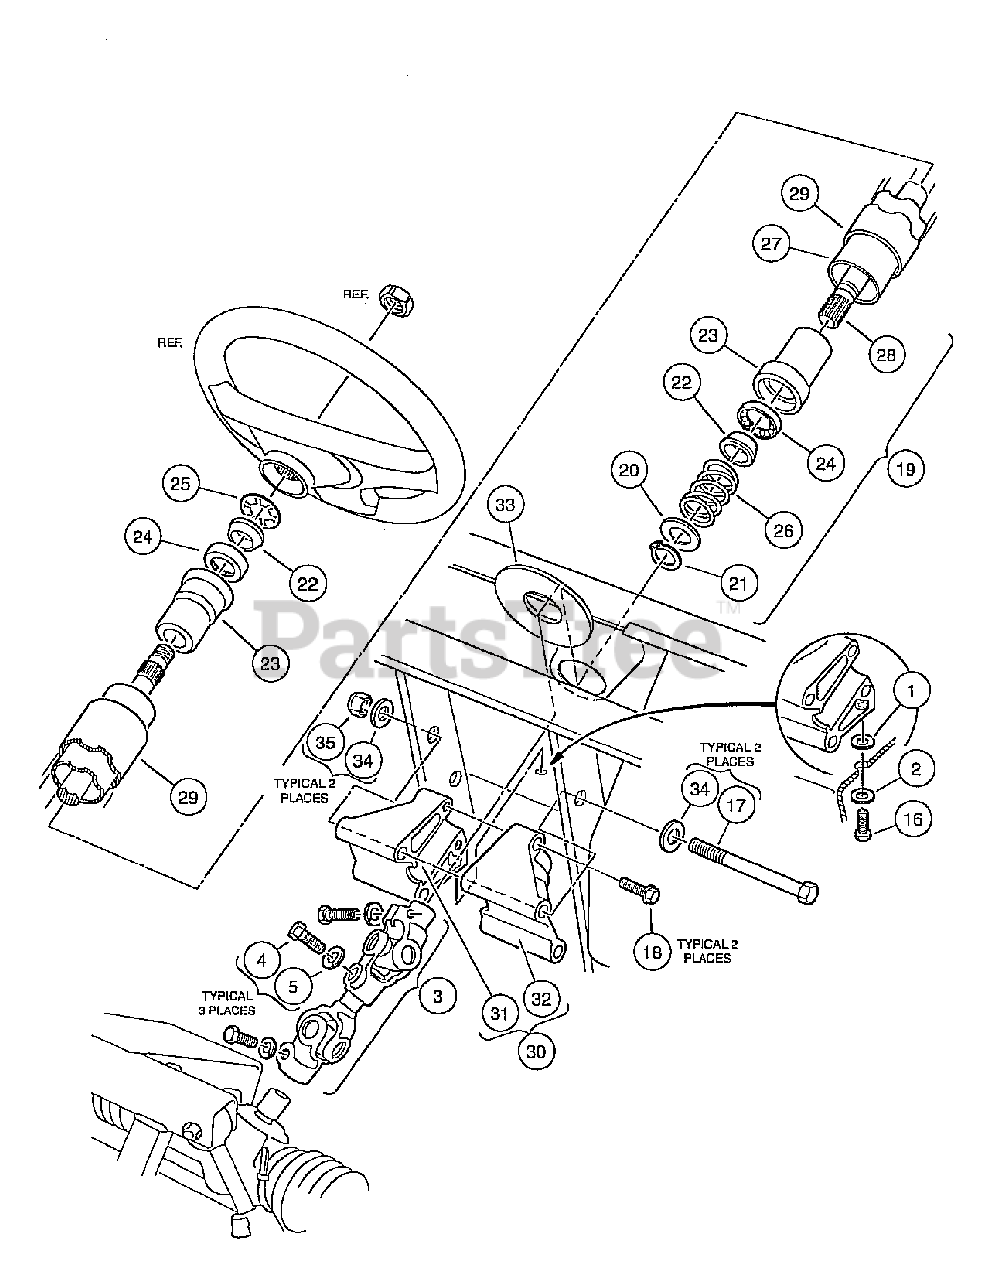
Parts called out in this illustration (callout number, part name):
1	Washer, 5/16 Type B Flat
2	Washer, 5/16 Flat
3	Intermediate Steering Shaft
4	Bolt, Hex-Head, 8mm X 1.25 - 30
5	Lockwasher, 5/16 Split
7	Dust Cover
8	Ring, 0.579 Internal Retaining
9	Wedge, Molded
10	Seat, Plastic Bearing
11	Seal, Bearing
12	Spacer, Shaft
13	Bearing, Ball
14	Ring, Retaining
15	Spring, Steering Shaft
16	Screw, 5/16-18 X 0.75 Thread-Forming
17	Screw, 3/8-16 X 7.00 Hex Cap
18	Screw, 5/16-18 Thrd Forming
19	Steering Shaft Assembly
20	Washer, 0.675 ID X 1.19 OD
21	Ring, 0.579 Internal Retaining
22	Wedge, Molded
23	Seat, Plastic Bearing
24	Bearing, Ball
25	Ring, Retaining
26	Spring, Steering Shaft
27	Column, Aluminum Steering
28	Shaft Steering Column
29	Tube Cover, Steering Column
30	Kit, Steering Column Mounting Bracket
31	Bracket, RH Steering Column Mount
32	Bracket, LH Steering column mount
33	Boot, Steering Column Round
34	Washer, 3/8 Type A Flat
35	Locknut, 3/8-16 Hex
